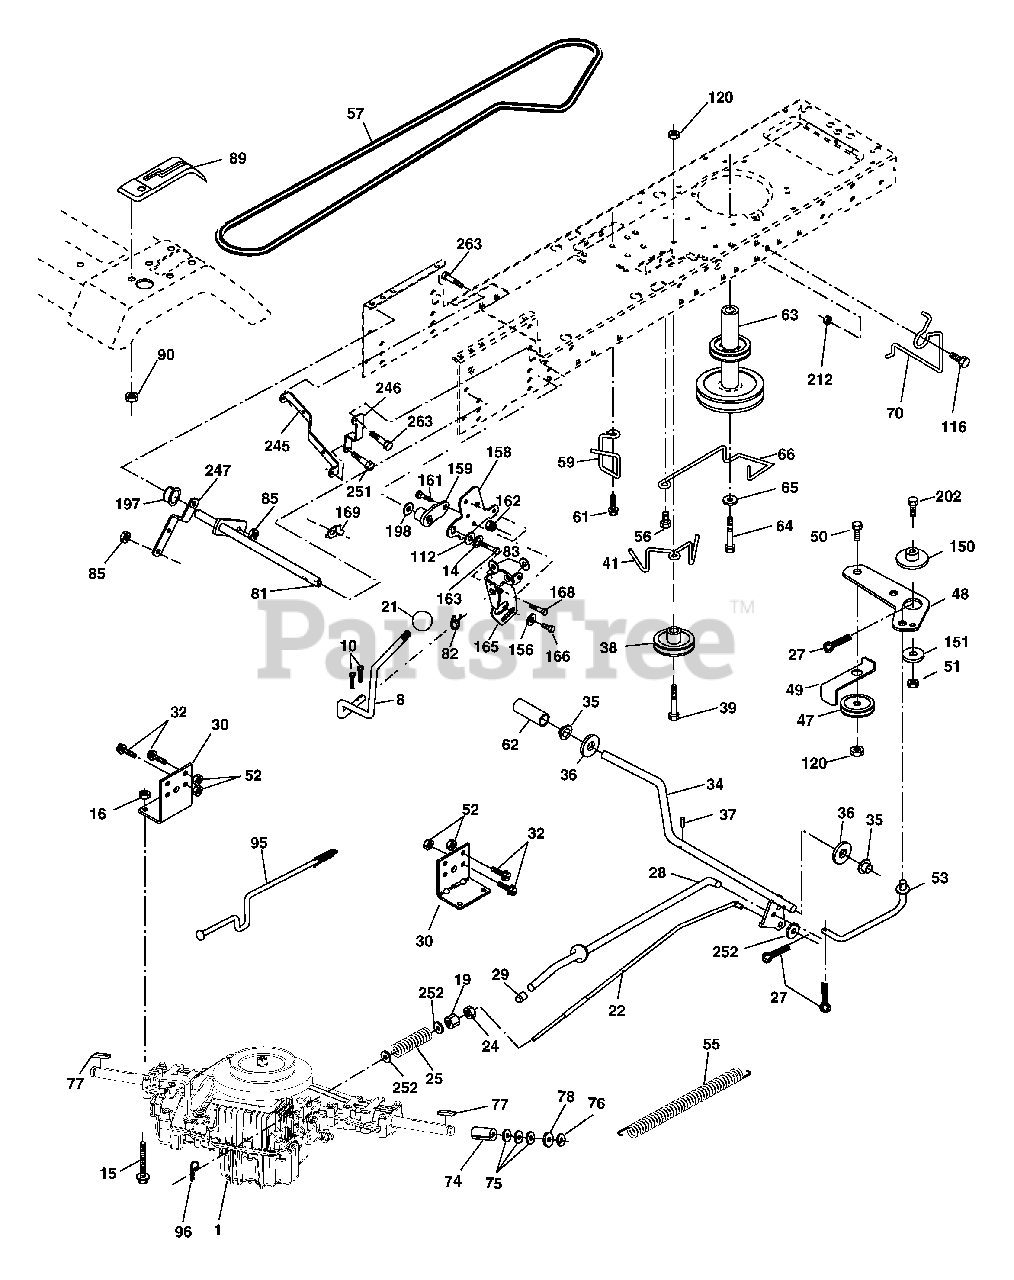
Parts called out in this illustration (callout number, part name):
1	Transaxle Peerless LTH 2000 (Order Parts From Transaxle Manufacturer)
8	Rod Shift
10	Pin Cotter 1/8 x 1 CAD
14	Washer Lock Hvy Helical
15	Bolt, Hex FLGHD 5/16-18 Gr. 5
16	Nut Lock Hex W/Ins 5/16-18 unc
19	Nut Lock Hex W/Wsh 3/8-16 unc
21	Knob, Round 1/2-13
22	Rod, Brake Hydro
24	Nut
25	Spring, Brake Rod
27	Pin Cotter 1/8 x 3/4 CAD.
28	Rod, Parking Brake
29	Cap, Parking Brake
30	Bracket, Transaxle
32	Bolt Hex Hd 5/16-18 unc x 3/4
34	Shaft, Foot Pedal
35	Bearing, Nylon
36	Washer
37	Pin, Roll
38	Pulley, Composite
39	Bolt Rdhd 3/8-16 unc x 2-3/4 Gr. 5
41	Keeper, Belt Idler
47	Pulley, Idler, V-Groove
48	Bellcrank Clutch Grnd Drv STL
49	Retainer, Belt
50	Bolt Carr Sh 3/8-16 x 1-1/2 Gr. 5
51	Nut Crownlock 3/8-16 unc
52	Nut Crownlock 5/16-18 unc
53	Link, Clutch
55	Spring, Return, Clutch
56	Screw 3/8-16 x 1-1/4
57	V-Belt, Ground Drive
59	Keeper, Center Span
61	Screw 3/8-16 x .875
62	Cover, Pedal
63	Pulley, Engine
64	Bolt Hex 7/16-20 x 4 x Gr. 5-1.5 Thr
65	Washer
66	Keeper Belt Engine
70	Guide Belt
74	Spacer, Axle
75	Washer 25/32 x 1-1/4 x 16 Ga.
76	E-Ring
77	Key, Square
78	Washer 25/32 x 1-5/8 x 16 Ga.
81	Shaft Asm. Cross Hydro
82	Spring Torsion T/A
83	Washer 17/32 x 3/4 x 16 Ga.
85	Nut Lock Center 1/4-28
89	Console, Shift
90	Screw Hex Wsh Hi-Lo 1/4-1/2 unc
95	Disconnect Asm. Rod Bypass LTH
96	Retainer Spring 1" Zinc/Cad
112	Washer 9/32 x 3/4 x 10 Ga.
116	Bolt RDHD SQNK 3/8-16 unc
120	Nut Lock Flg 3/8-16 unc
150	Spacer Retainer
151	Washer 13/32 x 2 x 10 Ga.
156	Washer Srrted 5/16 ID x 1.125
158	Bracket Shift Mount
159	Hub Shift
161	Bolt Rdhd Sqnk 1/4-20 x 3/4 Gr. 5
162	Nut Crownlock 1/4-20 unc
163	Bolt Hex Fin 1/4-20 unc x 1 Gr. 5
165	Bracket Pivot Lever
166	Screw 5/16-18 x 5/8
168	Bolt Shoulder 5/16-18 x .561
169	Plate Fastening Lt
197	Nyliner Snap-In 5/8" ID
198	Washer Nyl 7/8 ID x .105
202	Bolt Carr Sh 3/8-16 x 1-3/4 Gr. 5
212	Nut Hex fl ange Lock
245	Strap Torque LH
246	Strap Torque RH
247	Link Shift Transaxle
251	Screw 5/16-18 x 1
252	Washer 13/32 x 1 x 16 Ga.
263	Screw Hex Wsh Thdr 3/8-16 x 3/4
